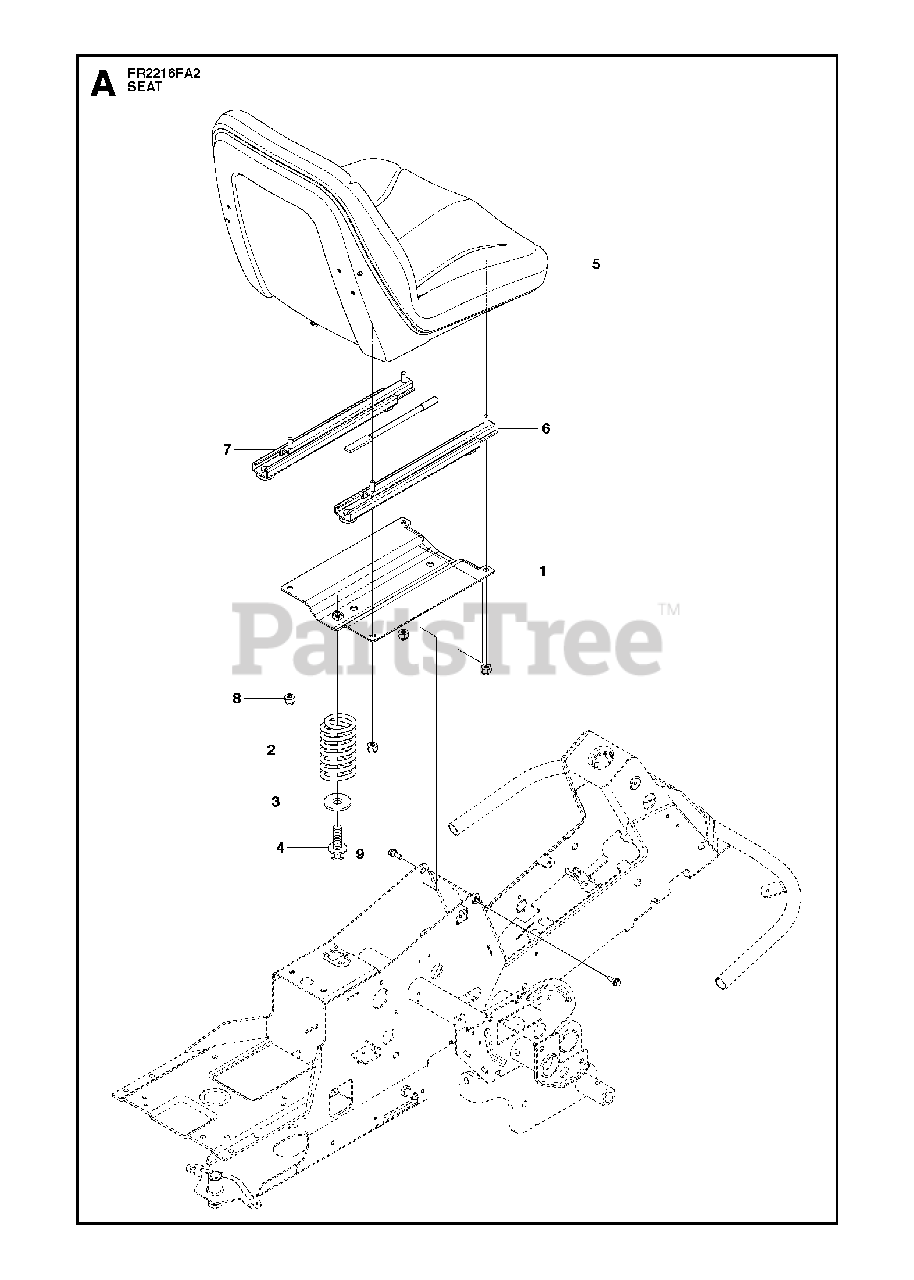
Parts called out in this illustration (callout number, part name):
2	SEAT SPRING
4	SCREW M10X25
8	LOCKNUT M8
